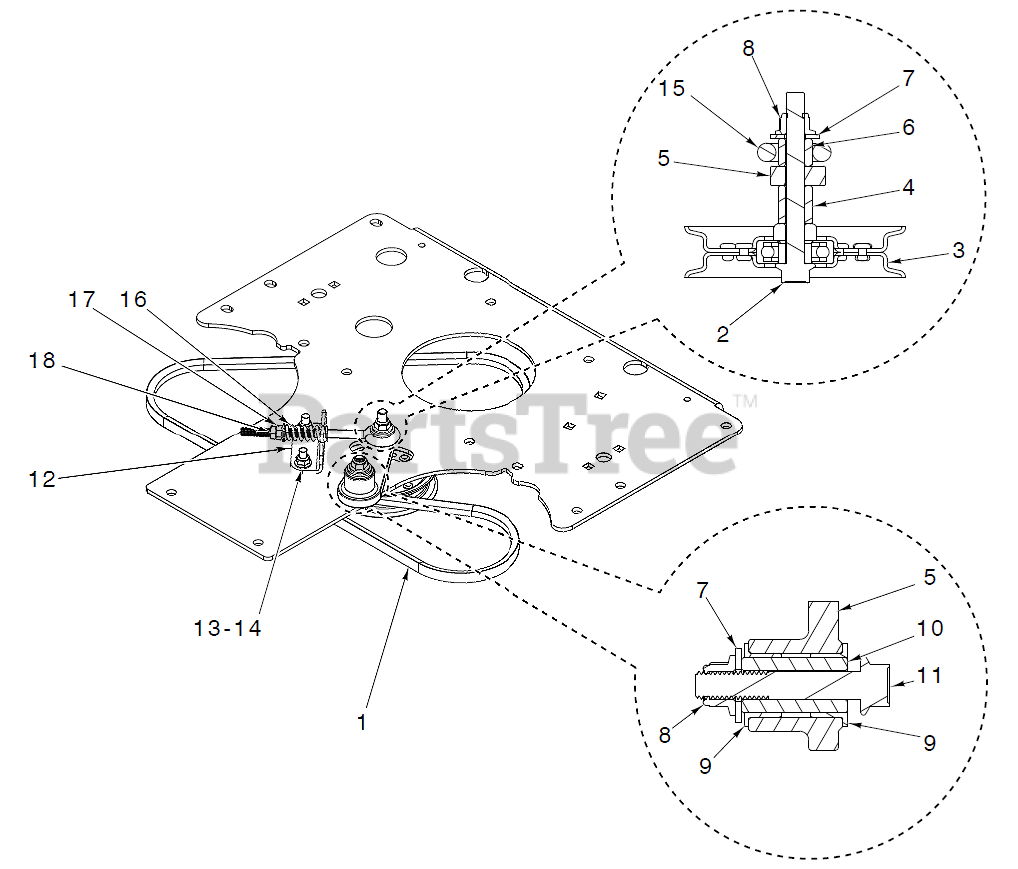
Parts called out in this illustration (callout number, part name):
1	Belts
2	HHFS 3/8-16 X 3.5 GD 5 ZD
3	Pulleys
4	Spacers
5	Arms
6	Spacers
7	GSPW Washers
8	GSPW Nuts
9	BEARING.FLANGED.PLASTIC.3/4ID
10	Spacers
11	HHFS 3/8-16 X 2.25 GD 8
12	Brackets
13	Bolts
14	NUT HEXAGON FLANGE 5/16-18 ST
15	Tensioners
16	SPRING, BRAKE ROD
17	Washers
18	NUT NUT.3/8-16.HEX.JAM.Z 3/8-1
